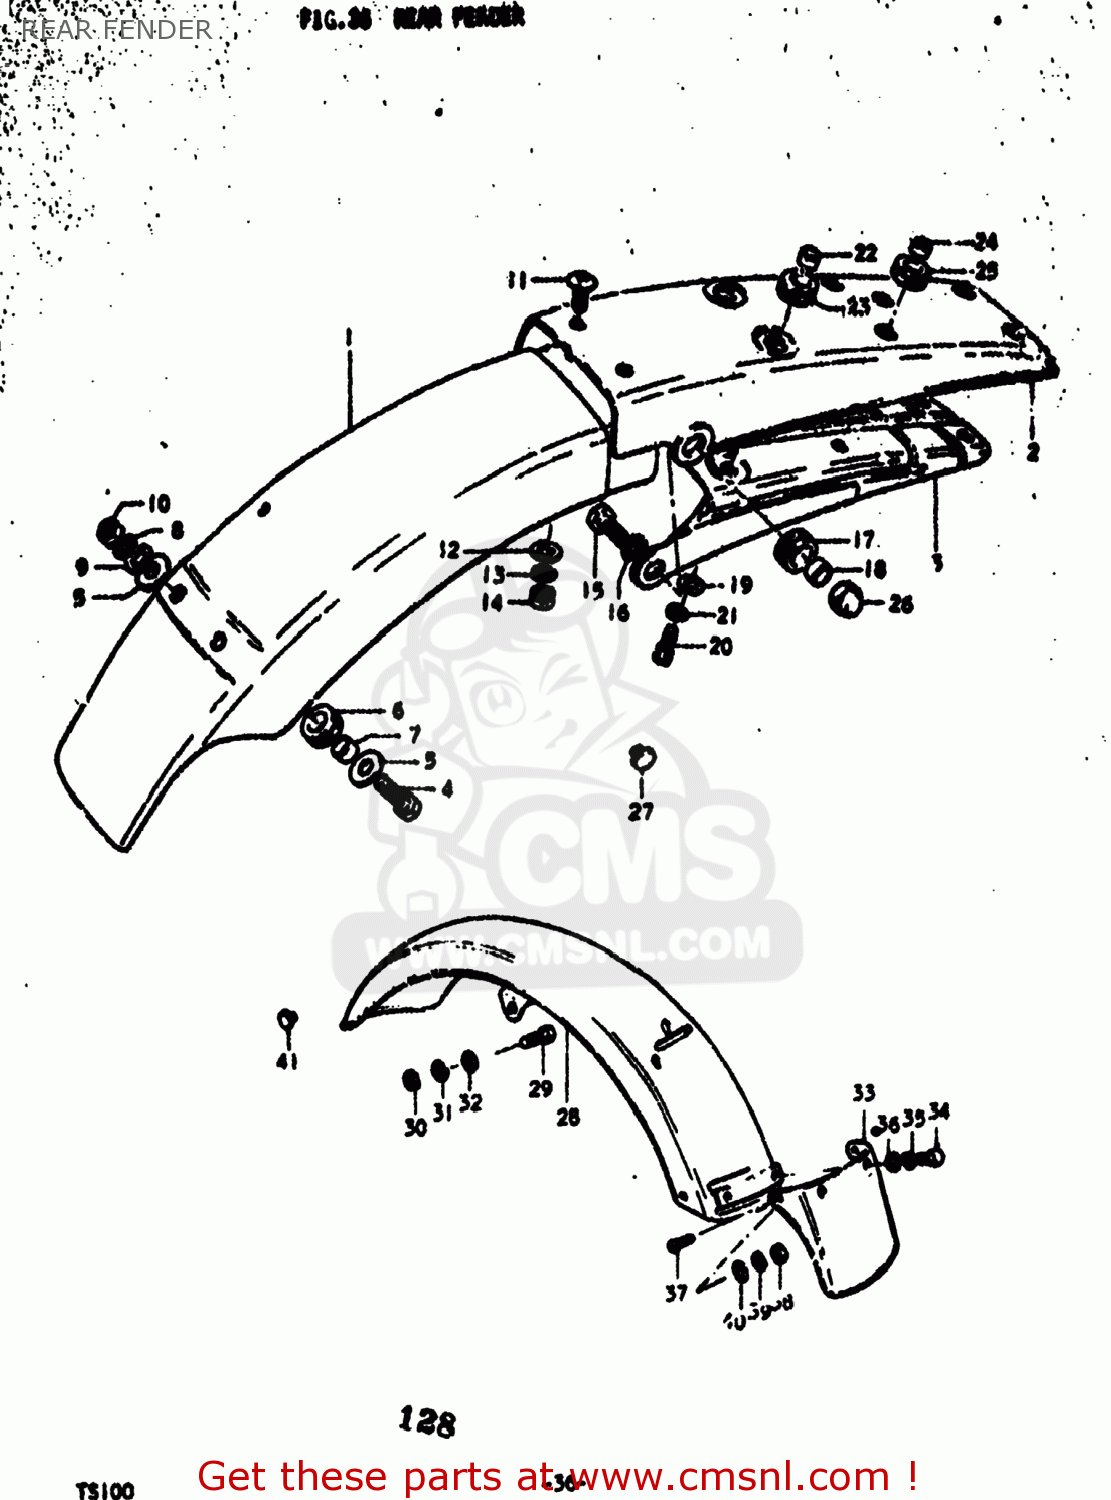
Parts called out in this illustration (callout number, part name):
1	FENDER,REAR
2	FENDER,REAR
3	REINFORCEMENT,REAR FENDER
4	BOLT
5	WASHER (6.5X20X1.2)
6	CUSHION
7	SPACER(6.1X9X7.5)
8	LOCK WASHER
9	WASHER
10	NUT
11	SCREW
12	WASHER 5MM
13	LOCK WASHER
14	NUT
15	Bolt 8X50
16	LOCK WASHER
17	CUSHION
18	SPACER
19	WASHER
20	BOLT
21	LOCK WASHER
22	SPACER (6.8X10X20)
23	CUSHION
24	SPACER
25	CUSHION
27	CUSHION
28	FENDER,REAR
29	BOLT 8X40
30	NUT
31	LOCK WASHER
32	WASHER
33	MUD GUARD,REAR FENDER
34	BOLT
35	LOCK WASHER
36	WASHER
37	SCREW
38	NUT
39	LOCK WASHER
40	WASHER
41	CUSHION
